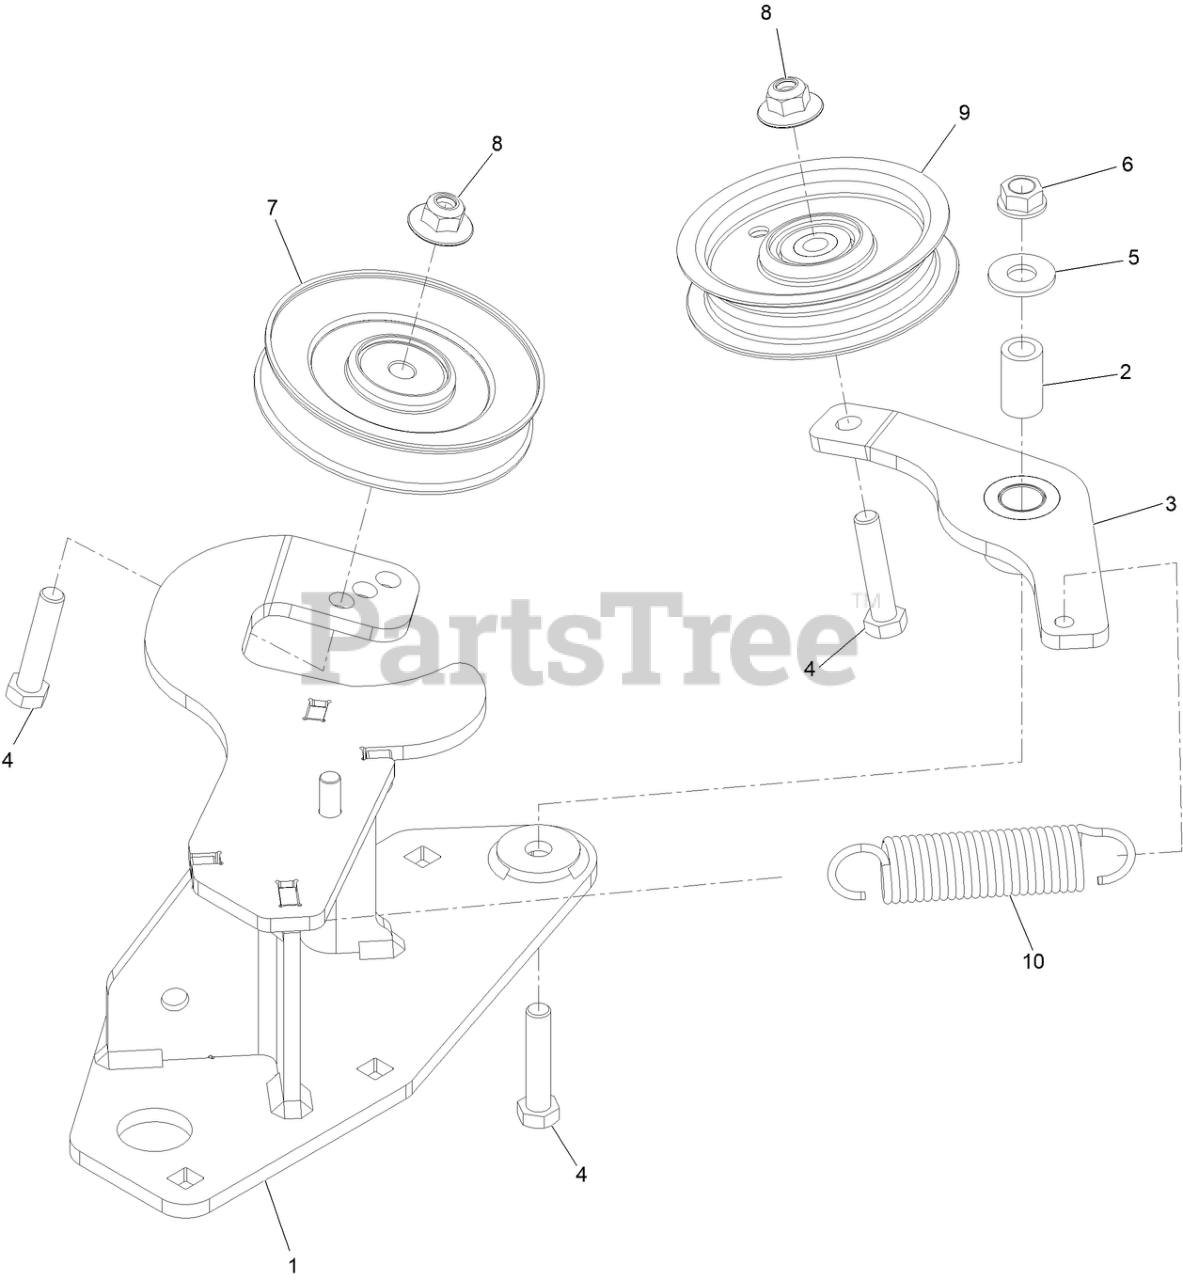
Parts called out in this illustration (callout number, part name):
1	Idler ASM-Blower [black]
2	BUSHING-PIVOT, IDLER
3	IDLER ASM
4	SCREW-HH
5	WASHER-FLAT
6	NUT-HHF, WHIZ
7	PULLEY-IDLER
8	Nut-Nyloc 3/8-16 Flg
9	PULLEY-IDLER, FLAT
10	SPRING-EXTENSION
